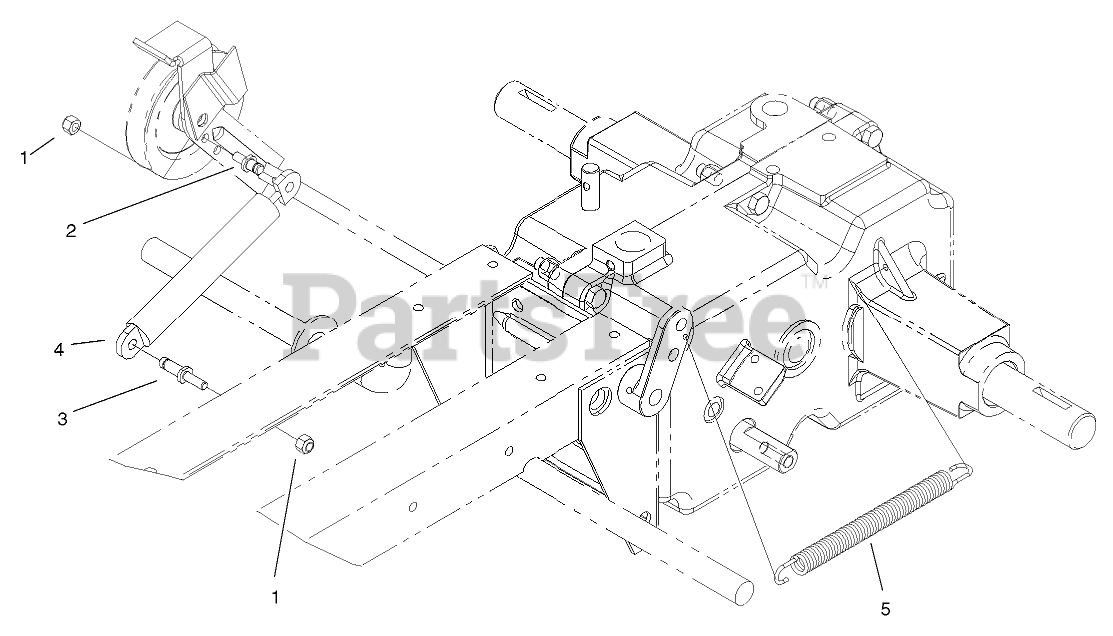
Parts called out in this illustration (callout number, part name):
1	NUT-LOCK, NI
2	PIN-DAMPER, CLUTCH ARM
3	PIN-DAMPER, CLASSIC FRAME
4	DAMPER-GAS
5	SPRING-CLUTCH
